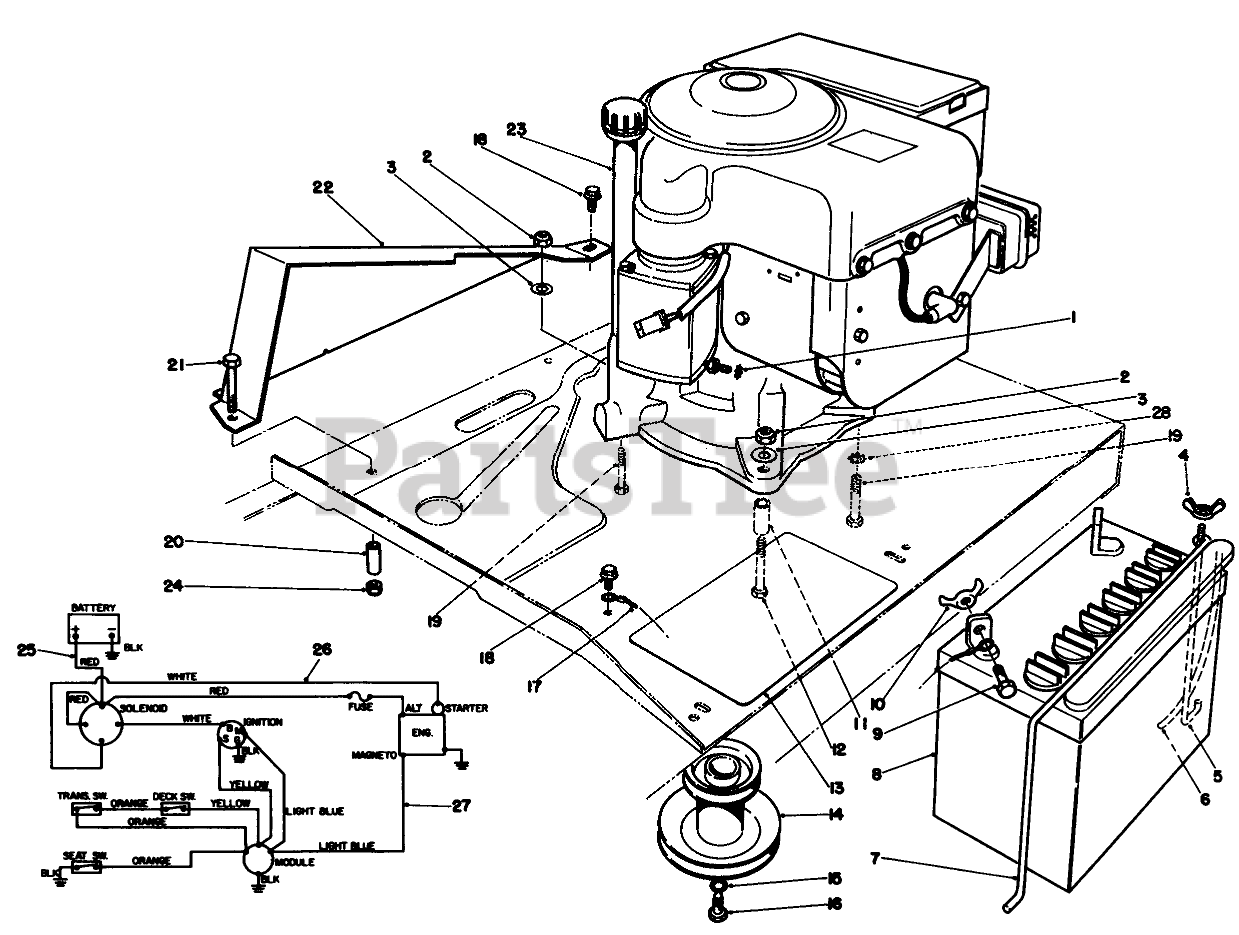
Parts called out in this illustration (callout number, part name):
1	WASHER-LOCK/EXT
2	NUT-LOCK, CONE
3	WASHER-PLAIN
4	NUT-WING SPECL
5	POST-BATTERY
6	TUBE-BATT DRAIN/80-2600
7	BATTERY HOLDOWN
8	Battery
9	SCREW-HH
10	NUT-WING
11	PIVOT SPACER
12	SCREW-HH
13	PAD-SKID, ANTI
14	Pulley-Engine
15	WASHER-LOCK
16	SCREW-HH
17	ENG-GROUND WIRE ASM
18	SCREW-HWHTF
19	SCREW-HH
20	GUIDE-BELT
21	SCREW-HH
22	GUIDE-CHAIN
24	NUT-LOCK, NI
25	WIRE ASM - BATT TO SOL
26	WIRE ASSEMBLY
27	WIRE HARNESS
28	WASHER-LOCK
